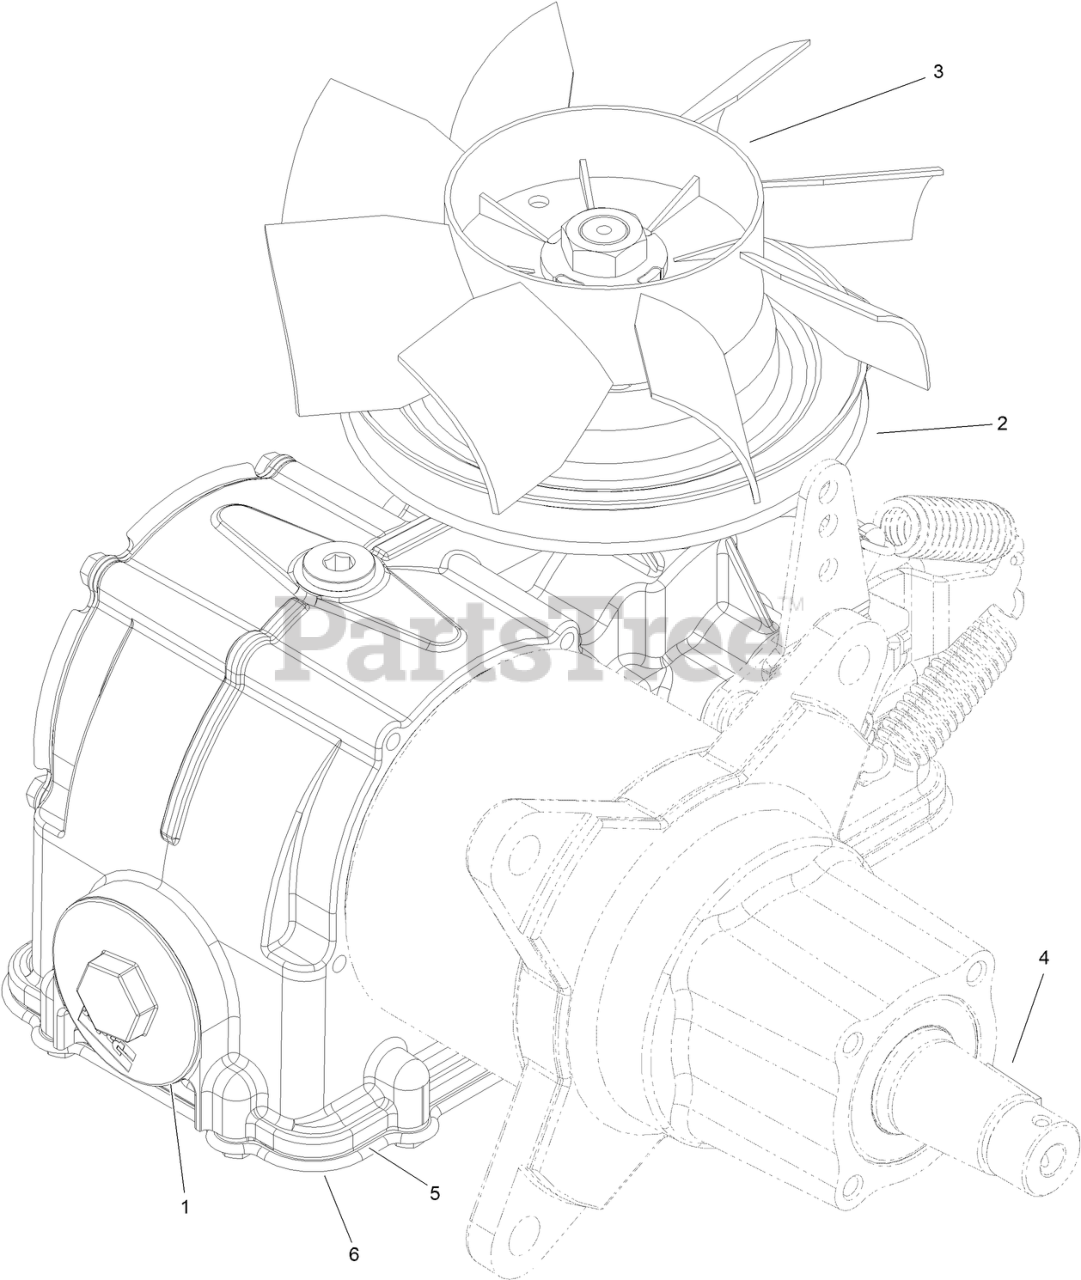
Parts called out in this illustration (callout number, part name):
1	FILTER
2	PULLEY
3	FAN (8.3 INCH)
4	KEY-WOODRUFF
5	GASKET-COVER, BOTTOM
6	COVER-SERVICE
